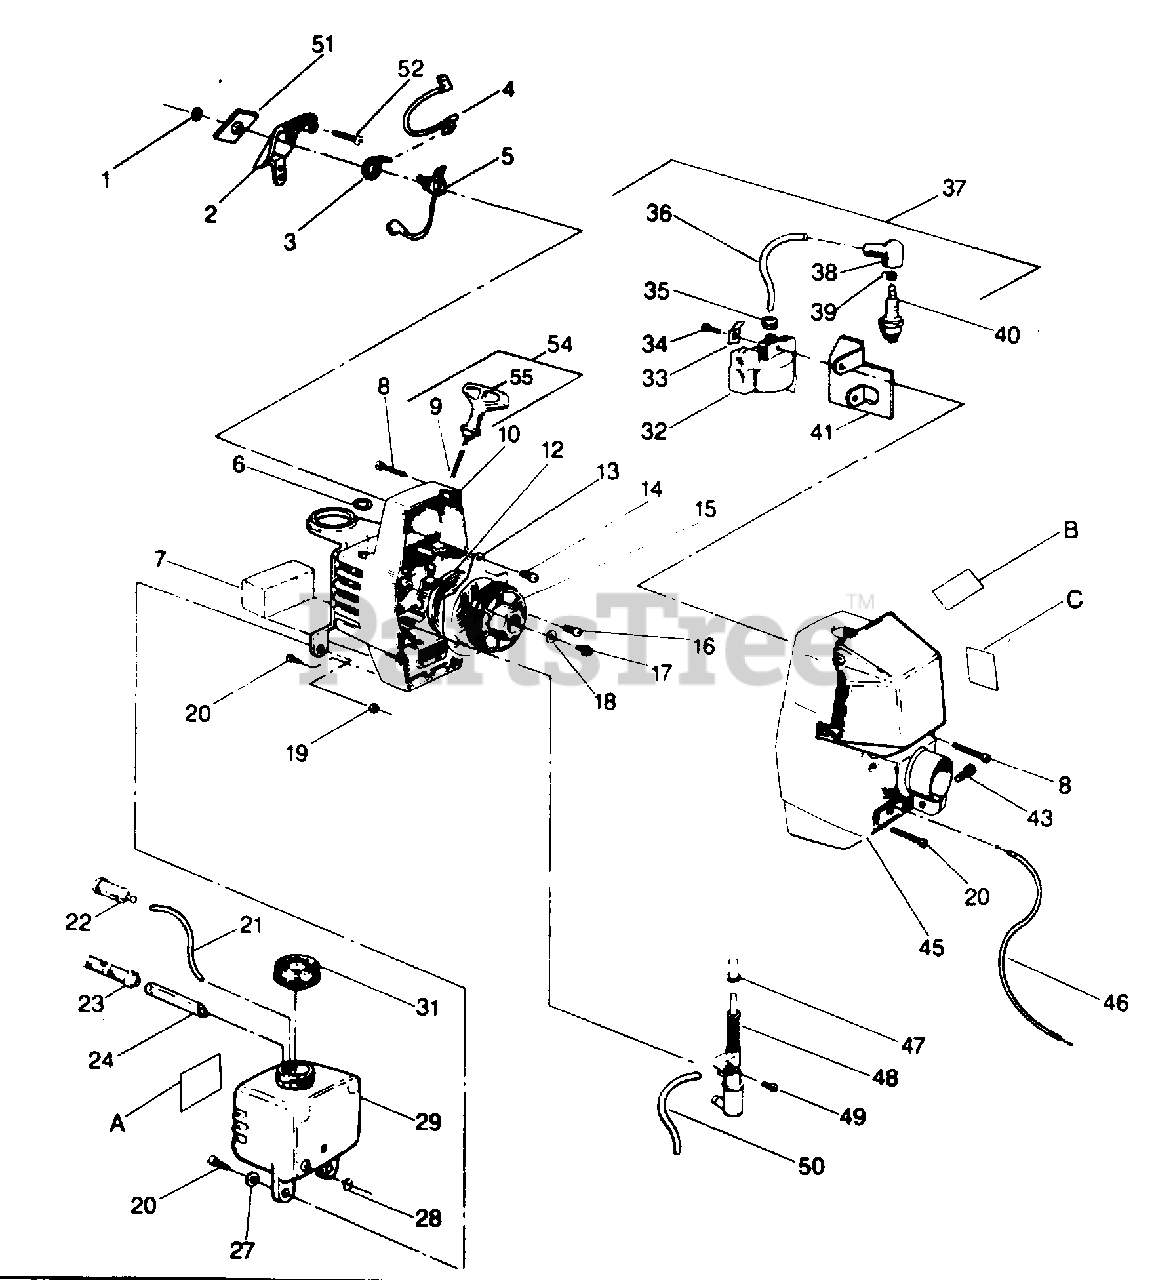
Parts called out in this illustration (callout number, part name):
1	Nut-Grounding Switch
2	Housing - Switch
3	Washer - Grounding Switch
4	Wire - Lead - Grounding Switch
5	Kit - Grounding Switch (incl. #34)
6	Bearing - Nyliner (Fan Housing)
7	Air Filter
8	Screw - #10 - 24 x 1-1/2" Fil. Hd. - Fan Housing Top
9	Rope Kit
10	Fan Housing Ass'y
12	Spring Starter Pulley
13	Air Baffle
14	Screw - 10 - 24 x 1/4 Pan. Hd. - Air Baffle
15	Starter Pulley
16	Screw - #10 - 24 x 7/16" - Air Baffle
17	Screw - #10 - 24 x 1/2" - Starter Pulley
18	Washer - #10 - Starter Pulley Screw
19	Nut - #10 - 24 - Fuel Tank Bracket
20	Screw - #10 - 24 x 5/8" Fil. Hd. Housing Bottom
21	Line Kit
22	Previous Style
22	Current Style
23	Filter - Fuel (Inlet Line)
24	Line - Fuel Inlet
27	Washer - Flat - Fuel Tank Bracket
28	Clip - Retainer - Inlet Line - Fuel Tank
29	Fuel Tank Ass'y (Incl. #21-24 & 31)
31	Fuel Cap Assembly
32	Kit Ignition Module
33	Electrical Tab
34	Screw - #8 - 32 x 3/4" - Fil. Hd. - Ignition Module
35	Grommet - Plug Wire
36	High Tension Lead Wire
37	BEVEL GEAR COMPLETE
38	Boot - Spark Plug
39	Connector - Spark Plug Lead
40	Spark Plug (CJ-14)
41	Deflector - Air
45	Ass'y - Shroud/Heat Shield
46	Throttle Cable
47	Injector Button
48	Pump Assembly (incl. #50)
49	Screw - #10 - 14 x 1-3/16" - Air Baffle-Pump Mounting
50	Line-Pump to Accumulator
51	Plate - Indicating Switch
52	Screw - #10 - 17 x 3/8" - Switch Plate
54	Ass'y - Rope & Handle
55	Starter Handle
A	Type 1 & 2
C	Decal - Shroud (Left)
